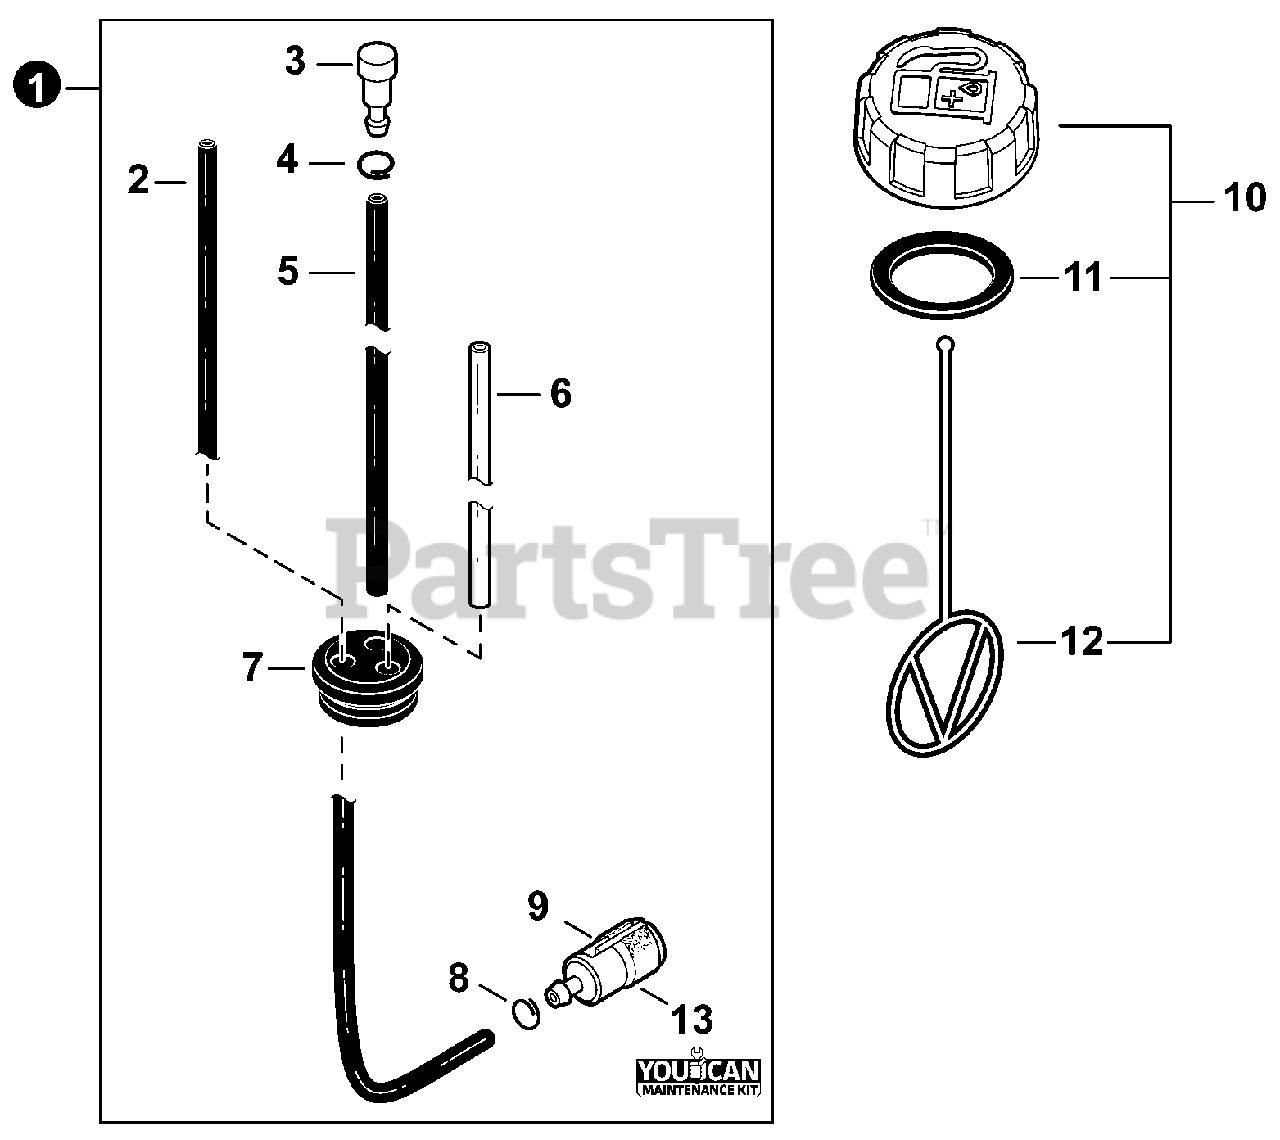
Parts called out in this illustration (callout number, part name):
1	FUEL SYSTEM KIT
2	PIPE, FUEL 3×5×195 BLACK
3	VENT ASSY
4	CLIP 6.5 MM
5	PIPE 3×6×115 BLACK
6	PIPE, FUEL 3×6×80 CLEAR
7	GROMMET, FUEL
8	CLIP 6 MM
9	FILTER, FUEL
10	CAP ASSY, FUEL
11	GASKET, FUEL CAP
12	CONNECTOR, CAP L= 100 MM
13	TUNE-UP KIT - YOUCANT
